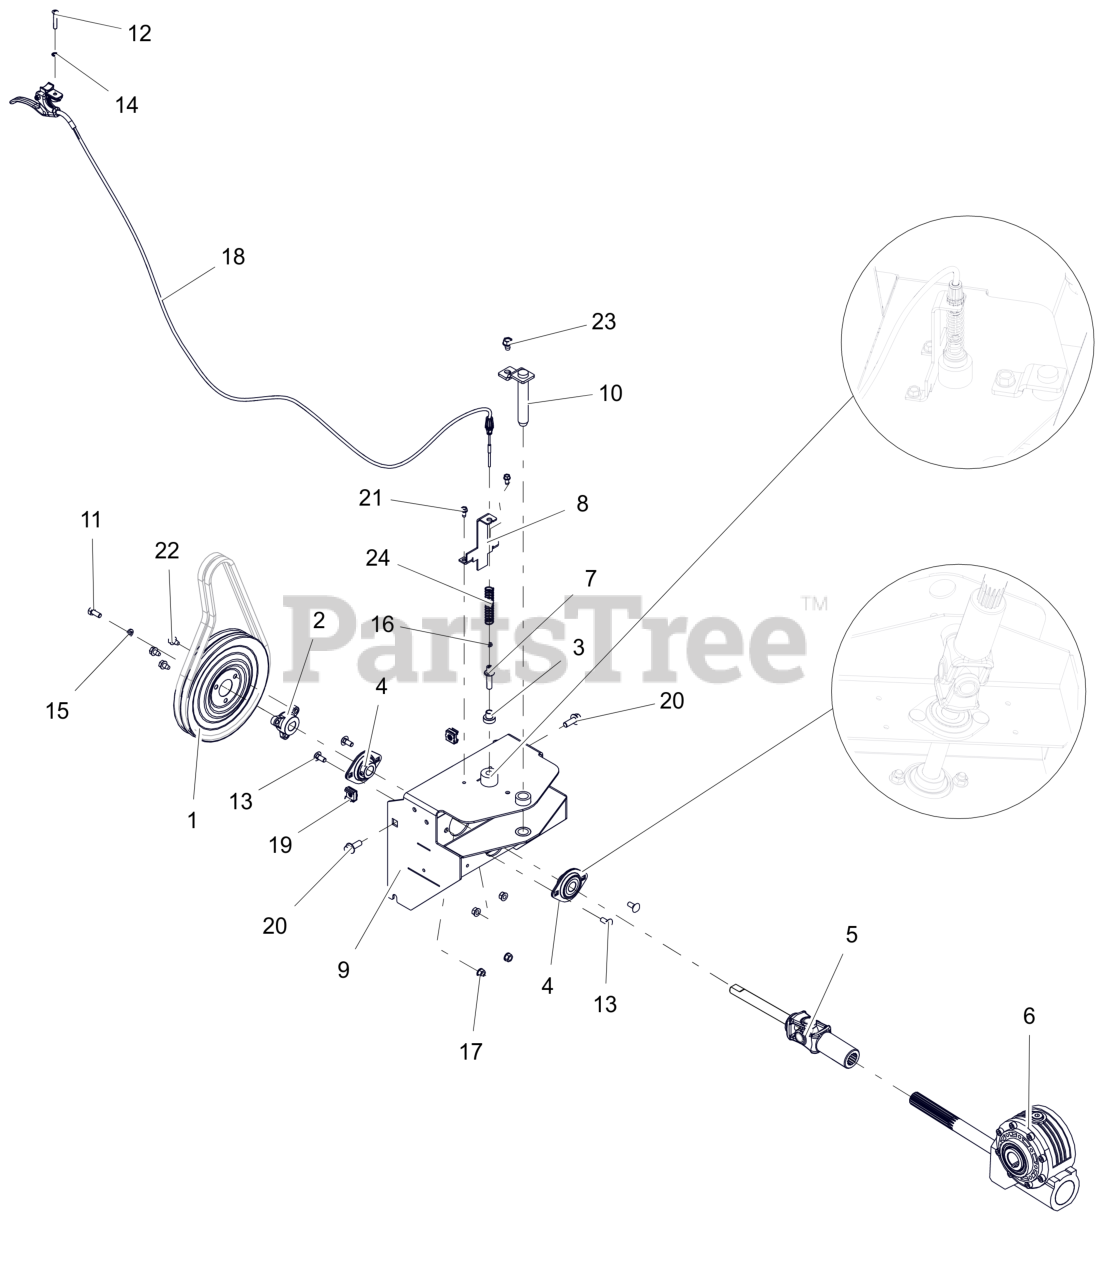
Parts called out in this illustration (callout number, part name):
1	PULLEY, SPIN FORM DUAL GROOVE
2	PULLEY HUB, BOLT-ON D-BORE .75
3	SPACER -FLANGED .390X.500X.781
4	BEARING, 2 BOLT FLANGE -.75 ID
5	DRIVELINE, SERIES 07 (U-JOINT)
6	GEARBOX, WORM - 8.25:1
7	PIN, ADJUSTABLE ANGLE BRUSH
8	BRKT, PIN HOLDER
9	ADAPTER, BRUSH
10	WLDMT, BRUSH PIN
11	BLT, HEX .31-24X.750 G5 ZCC
12	SCR,OVAL .25-20X1.50 ZCC
13	BLT,RHSN .31-18X.75 G5 ZCC
14	WSHR-LK-INT .250 TH TYA
15	WSHR, LK-HVY .312X.097 ZCC
16	NUT, HEX #10-24 ZCC
17	NUT-LK-TOP-FLG .312-18 GF ZCC
18	CABLE, REMOTE BRUSH LOCK
19	NUT-RETNR .38-16 TINRMAN
20	BLT, SERHFWH .38-16X1.00 ZCC
21	SCR-TAP .25-20X.50 HWH ZCC
22	SCR,TAP .312-18X.50 HWH TR ZCC
23	SCR,TAP .375-16X.50 HWH TR ZCC
24	SPRING, COMPRESSION
